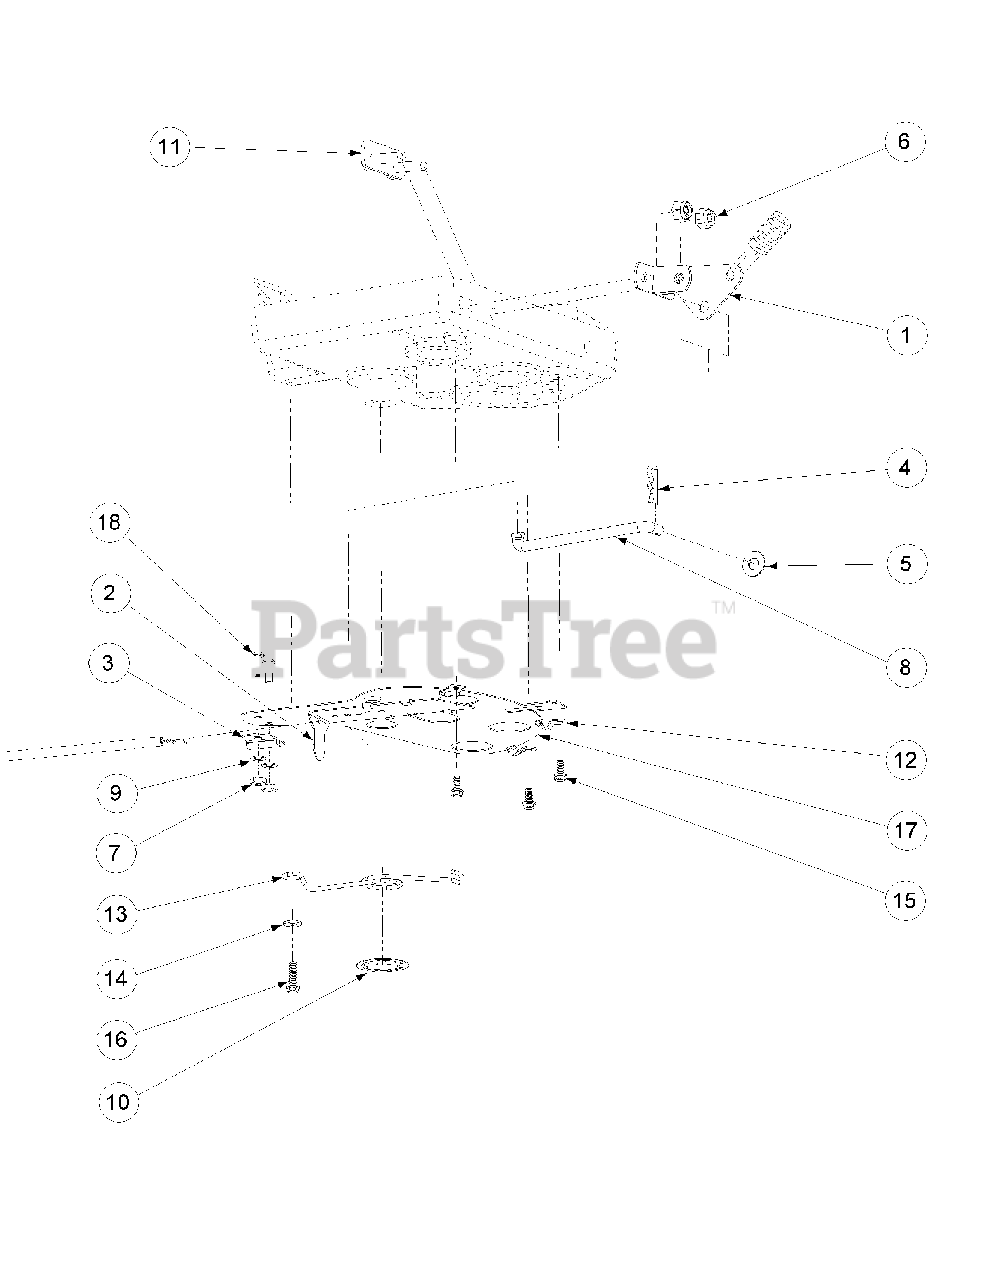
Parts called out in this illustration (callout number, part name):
1	Pivot Lever ASsembly
2	Slide Lever
3	Remote Third Hole Wire Bracket
4	Cotter Pin
5	Washer, 1/4, SS
6	Nut, 1/4-20, SS
7	Nut, 8-32
8	Pivot Lever Rod
9	Lock Washer
10	Spring Clip
11	Pivot Assmebly Mounting Plate
12	Shut-Off Plate Clip
13	Shut-Off Plate Spring
14	Washer, #8, SS
15	Screw, #8 x 3/8, SS
16	Screw, #8 x 5/8, SS
17	Shut-Off Plate
18	Hex Cap Screw, 8-32 x 1/2, SS
